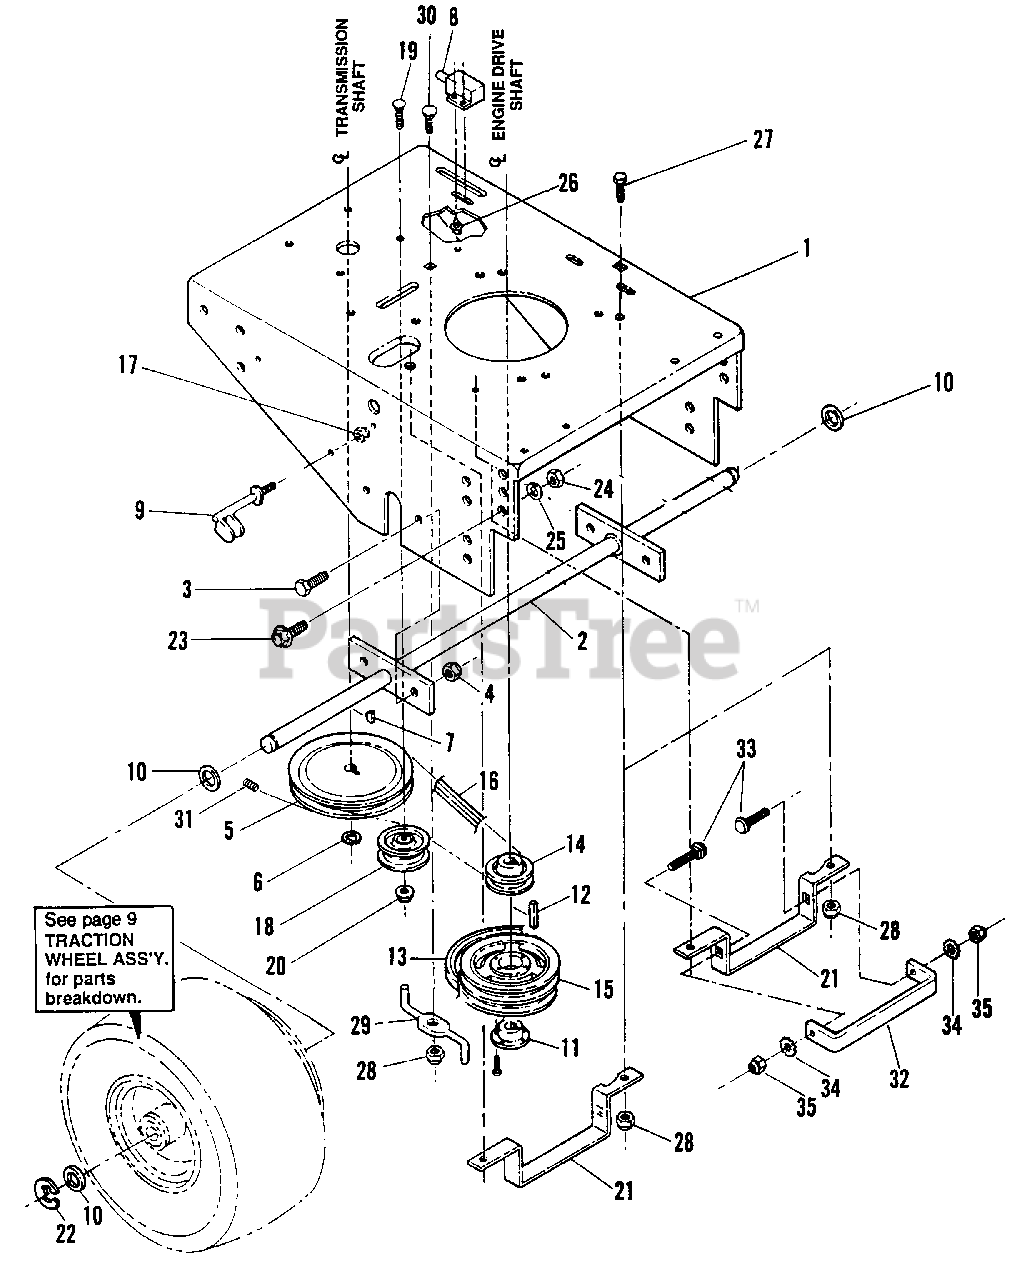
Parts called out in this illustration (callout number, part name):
1	REAR DECK WELDMENT
2	AXLE WELDMENT
3	SCREW, 3/8" C x 1", Hex, Cap
4	NUT, 3/8" C, Nyloc
5	PULLEY, Transmission
6	SNAP RING, 5/8"
7	KEY, Woodruff 09
8	SWITCH, Blade
9	SCRAPER, Wheel
10	BUSHING, Axle
11	BUSHING, Taperlock
12	KEY, Sq. 1/4" x 2 1/2"
13	BELT, Engine/Deck 36"
14	PULLEY, Engine/Transmission
15	PULLEY, Engine/Deck
16	BELT, Engine/Transmission
17	NUT, 3/8" F, Hex.
18	PULLEY,Idler
19	BOLT, 3/8C x 1-3/4" Grade 5 Carriage
20	NUT, 3/8C Nyloc
21	BELT GUIDE, Engine
22	E-RING, 1"
23	BOLT, 1/2" C x 1- 1/4", Hex. Flange
24	NUT, 1/2" C
25	WASHER, 1/2" Lock
26	SCREW, #12 - 14 x 1/2" Lg. Hex Fig. Self-Tapping
27	BOLT, 5/16 x 3/4" Hex
28	NUT, 5/16" Nyloc
29	BELT KEEPER
30	BOLT, 5/16" x 1" Carriage
31	SETSCREW, 1/4-20 x 5/16" Knurled Cup Point w/ patch lock
32	SUPPORT, Belt
33	BOLT, 1/4C x 1" Grade 2 Carriage
34	LOCKWASHER, 1/4" Int/External Tooth
35	NUT, 1/4C Nyloc
